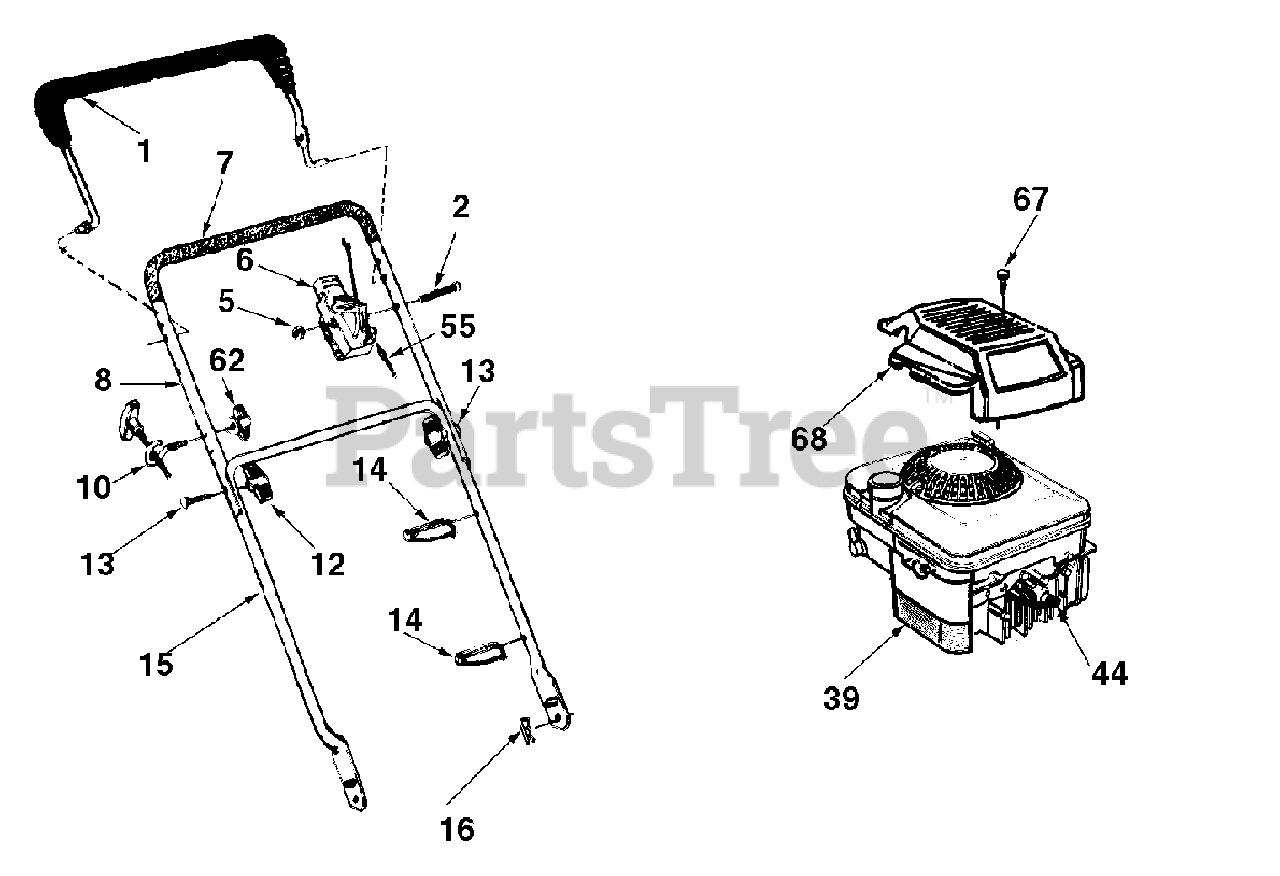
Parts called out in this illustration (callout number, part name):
1	Control Handle Ass'y.
2	Oval C-Sunk Screw
5	Hex Lock Nut
6	Control Housing
7	Foam Grip
8	Upper Handle
12	Hand Knob
13	Carriage Bolt
14	Cable Tie
15	Lower Handle
16	Hairpin Clip
39	Engine
44	Spark Plug Boot
55	Control Cable
67	Hi-Lo Screw
68	Engine Shroud
777D00299	Hub Caps
777D00587	Label Engine
777D02249	Label Engine
